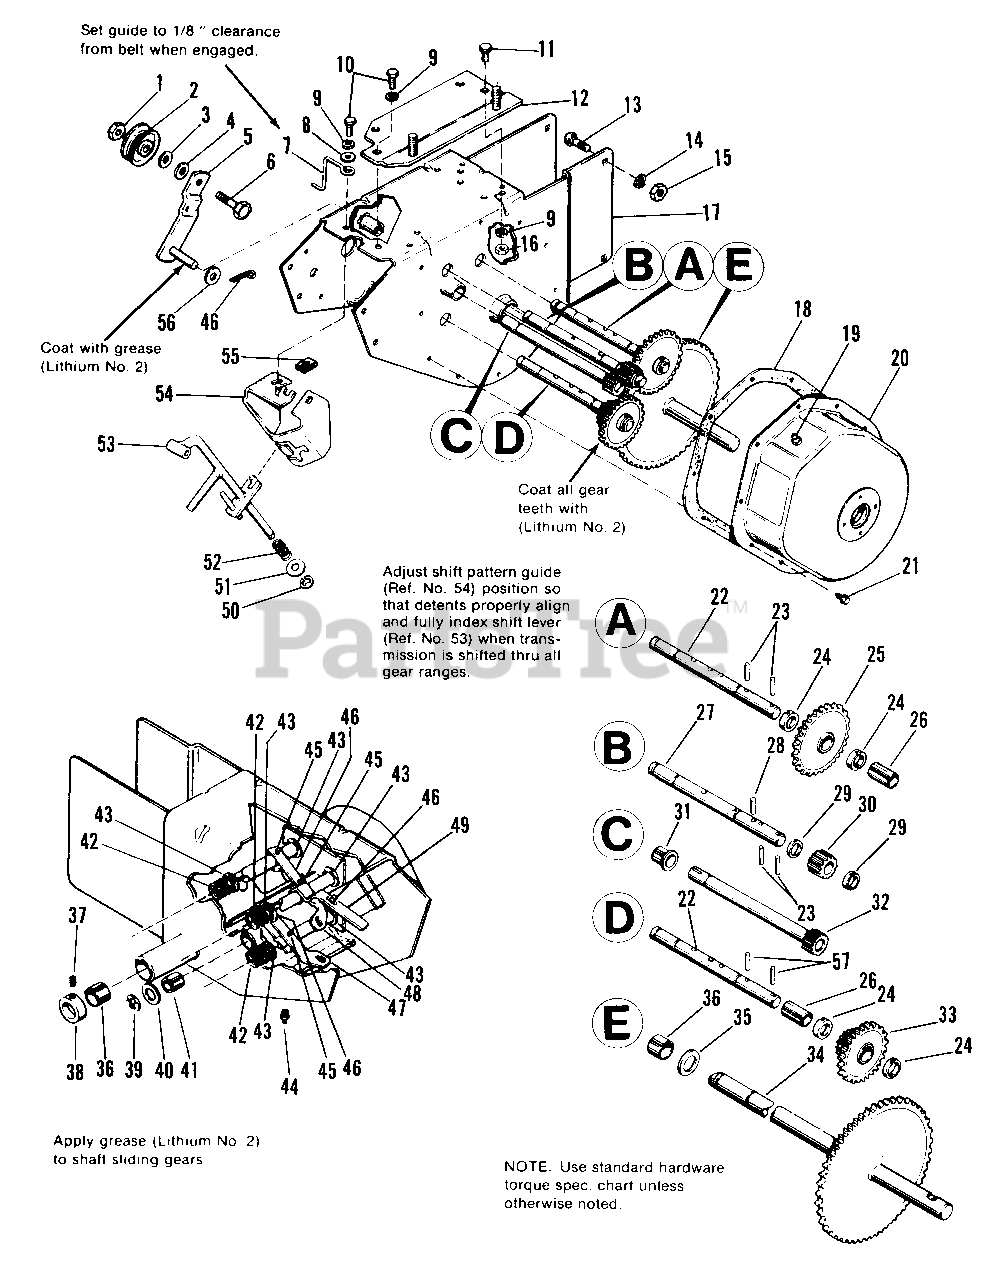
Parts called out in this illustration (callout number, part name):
1	LOCKNUT, Hex, Flange, 3/8-16
2	PULLEY ASSY.
4	WASHER, Plain, 5/16
5	ARM ASSY., Idler
6	CAPSCREW, Hex Hd., 3/8-16 x 1-1/4
7	STOP, Belt
8	WASHER, Plain, 1/4
9	WASHER, Plain, 5/16 (Qty. 2 used on 524 & 724)
10	CAPSCREW, Hex Hd., 5/16-18 x 1
11	CAPSCREW, Hex Hd., 5/16-18 x 3/4 (828 & 1028)
12	SUPPORT ASSY., Engine (828 & 1028)
13	BOLT, Carriage, 3/8-16 x 3/4
14	LOCKWASHER, 3/8
15	NUT, Hex, Full, 3/8-16
16	NUT, Hex, Full, 5/16-18 (828 & 1028)
17	ENGINE BASE & FRAME ASSY.
19	FITTING, Grease
20	CASE ASSY., Gear
21	SCREW, Hex, Taptite, 1/4-20 x 3/8
22	SHAFT, Intermediate
23	PIN, Spring, 1/8 x 1
24	COLLAR, Thrust
25	GEAR & BEARING ASSY.
27	SHAFT, Reverse
28	PIN, Spring, 5/32 x 1
29	COLLAR, Thrust
30	PINION, Reverse
31	BEARING, Bronze
32	SHAFT ASSY., Gear
33	GEAR & BEARING ASSY.
34	AXLE & GEAR ASSY.
35	WASHER, Special
37	SETSCREW, 5/16-18 x 3/8
38	COLLAR, Set
39	RING, Retaining
43	RING, Retaining
44	FITTING, Grease
45	PIN, Cotter, 3/16 x 1-1/4
46	PIN, Cotter, 3/32 x 3/4
47	LINK, Shift, High
48	LINK, Shift, Lo
49	LINK, Shift, Reverse
50	RING, Retaining
51	WASHER, Plain, 7/16
53	ROD ASSY., Shift, Lower
54	GUIDE, Pattern
55	NUT, Retainer, 5/16-18
57	PIN, Spring, 1/8 x 3/4
